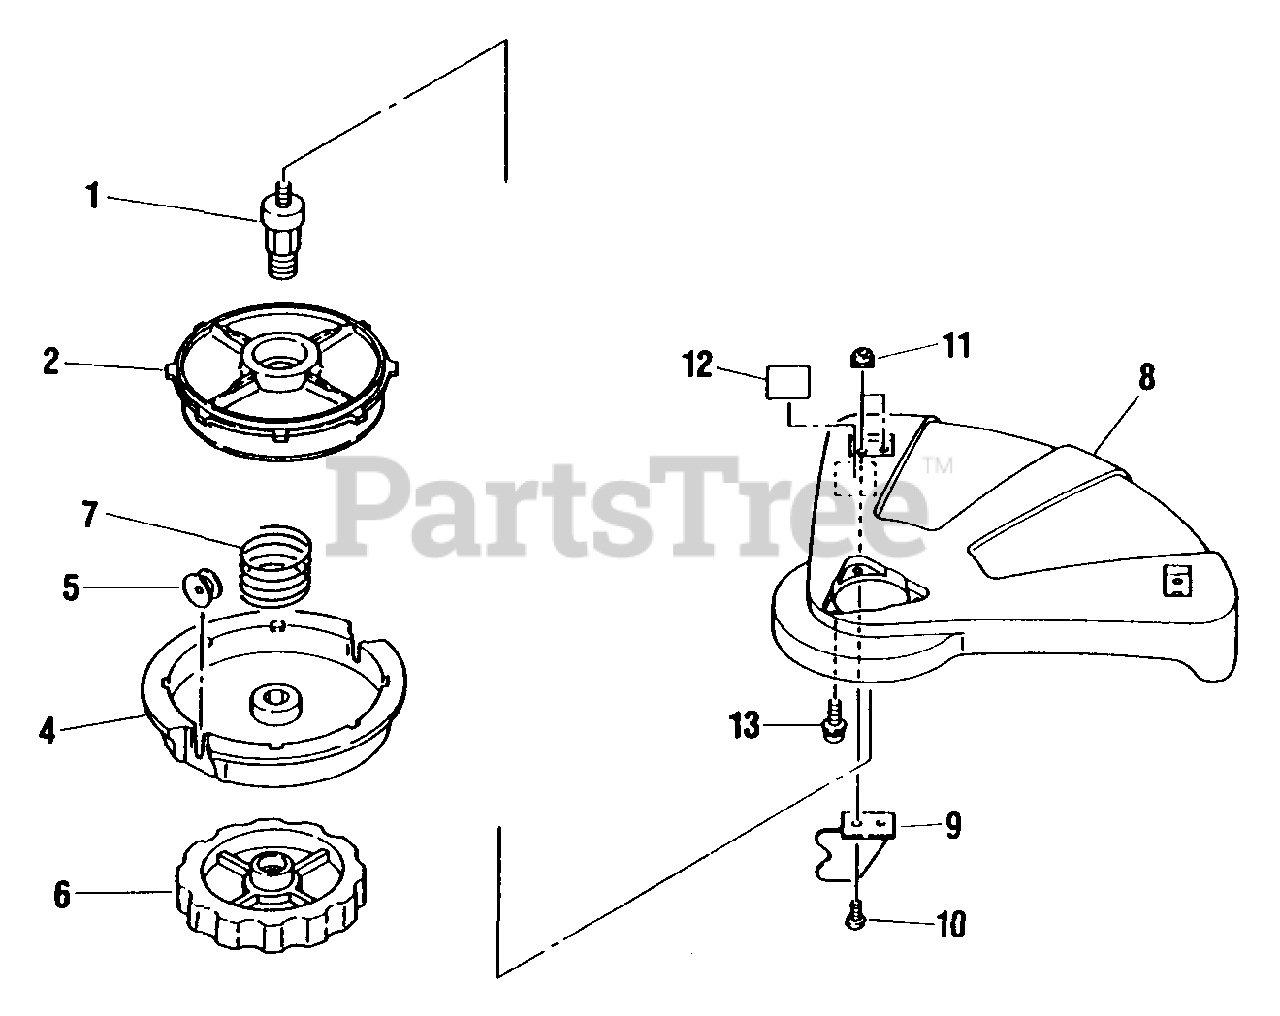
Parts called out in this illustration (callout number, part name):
1	SHAFT BOLT (8 MM RH)
2	INNER SPOOL
4	SPOOL HOUSING
5	EYELET
6	KNOB
7	SPRING
8	GUARD
9	KNIFE, TRIMMER LINE
10	SCREW
11	NUT - NYLON
12	LABEL, CAUTION
13	SCREW M5×16
